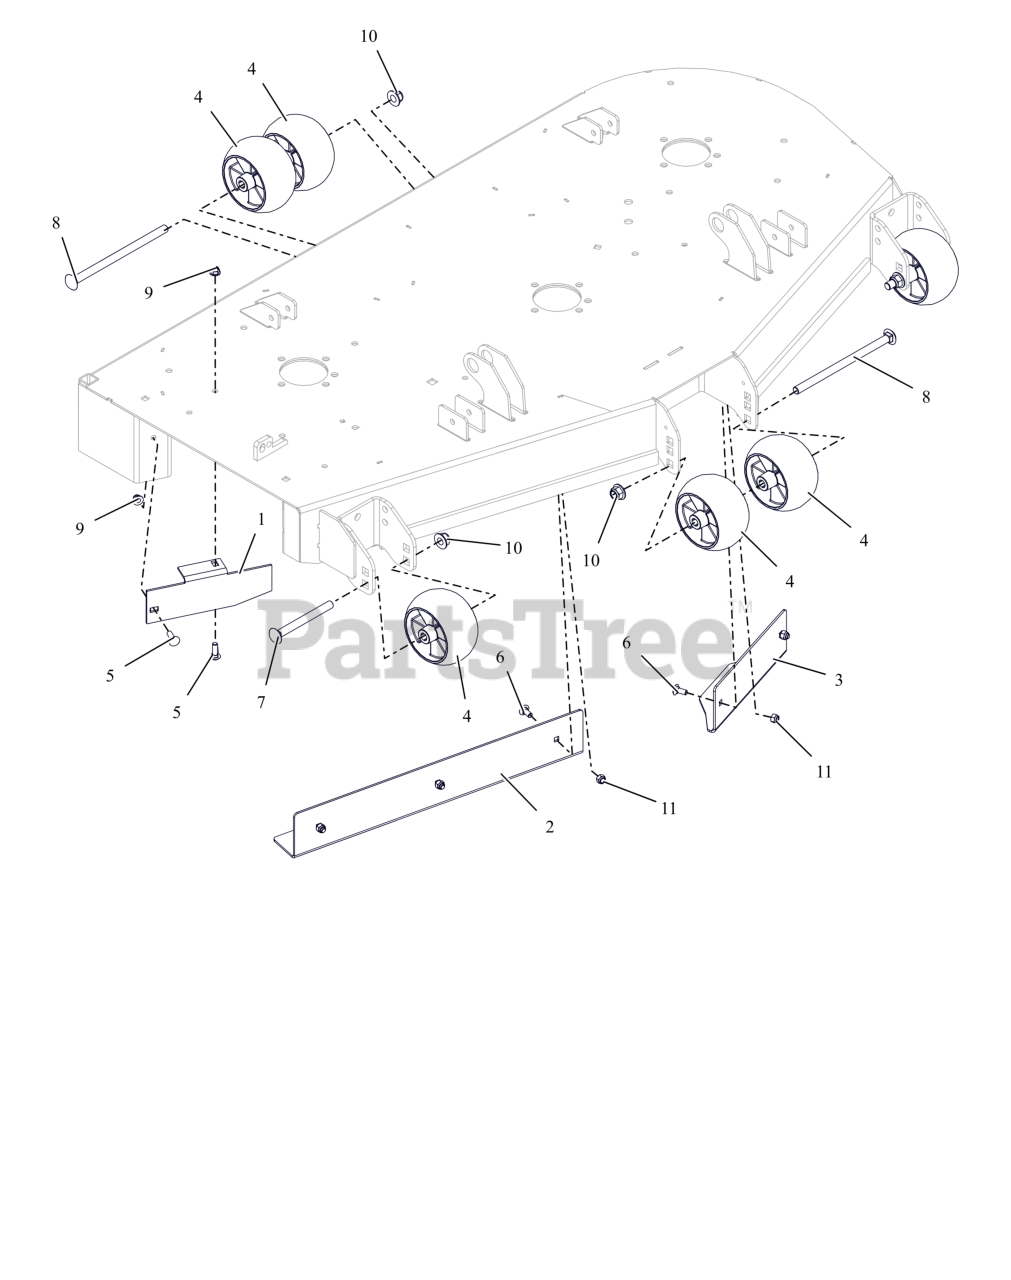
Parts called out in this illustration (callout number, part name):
1	BAFFLE, DISCHARGE, 52"
2	BAFFLE, 52" RH VACUUM (RED)
3	BAFFLE, 52" LH VACUUM (RED)
4	WHEEL, ANTI SCALP - 5X3 CTR W/RIBS
5	BLT,RHSN .31-18X1.00 G5 ZCC
6	BLT,RHSN .31-18X.75 G5 ZCC
7	BLT, RHSN .50-13X5.00 G5 ZCC
8	BTL,RHSN .500-13 X 8.5S G5 ZCC
9	NUT,NYL-FLG .31-18 GF ZCC
10	NUT,NYL-FLG .50-13 GF ZCC
11	NUT,NYL .31-18 G5 ZCC
